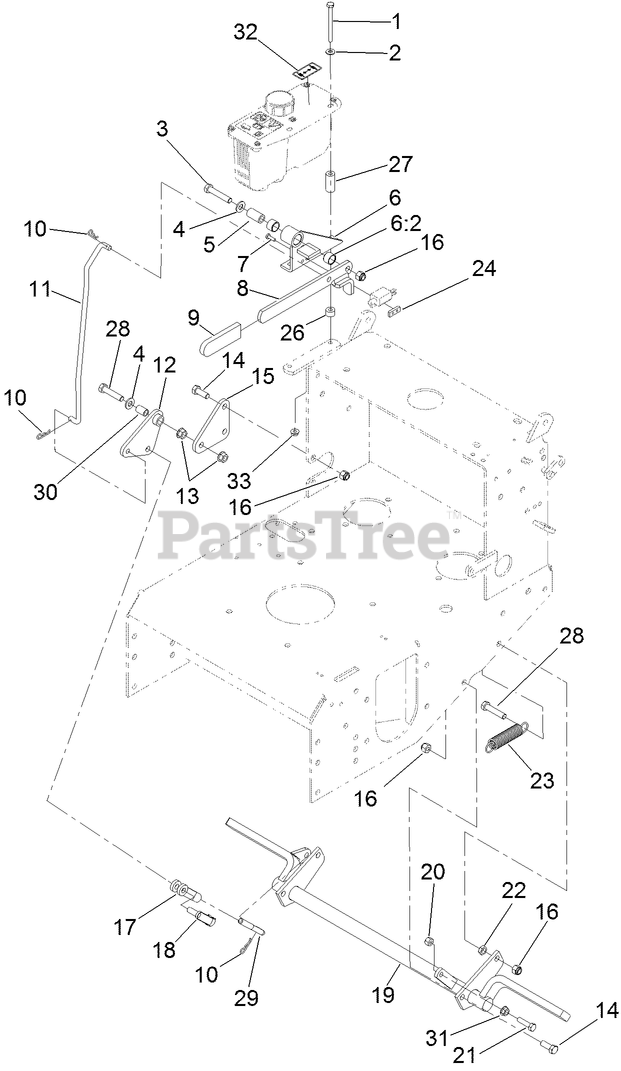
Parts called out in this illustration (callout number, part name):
1	SCREW-HH
2	WASHER-FLAT
3	SCREW-HH
4	WASHER-FLAT
5	Bushing-Pivot
6	Bracket ASM
6:2	SLEEVE-BUSHING
7	SCREW-PPH
8	PARK BRAKE LEVER
9	GRIP-LEVER
10	PIN-COTTER
11	Linkage-Upper
12	Bellcrank ASM
13	NUT-HF
14	SCREW-HH
15	Bellcrank
16	NUT-LOCK, NI
17	YOKE-LINKAGE, BRAKE
18	Pin-Spring, Clevis
19	BRAKE ASM
20	NUT-LOCK, NI
21	SCREW-HH, SPECIAL
22	NUT-JAM
23	SPRING-IDLER
24	PLATE-TAPPED
26	SPACER
27	Spacer
28	SCREW-HH
29	Linkage-Lower
30	Bushing-Plastic
31	NUT-HF
32	DECAL-BRAKE, PARK
33	NUT-HF
